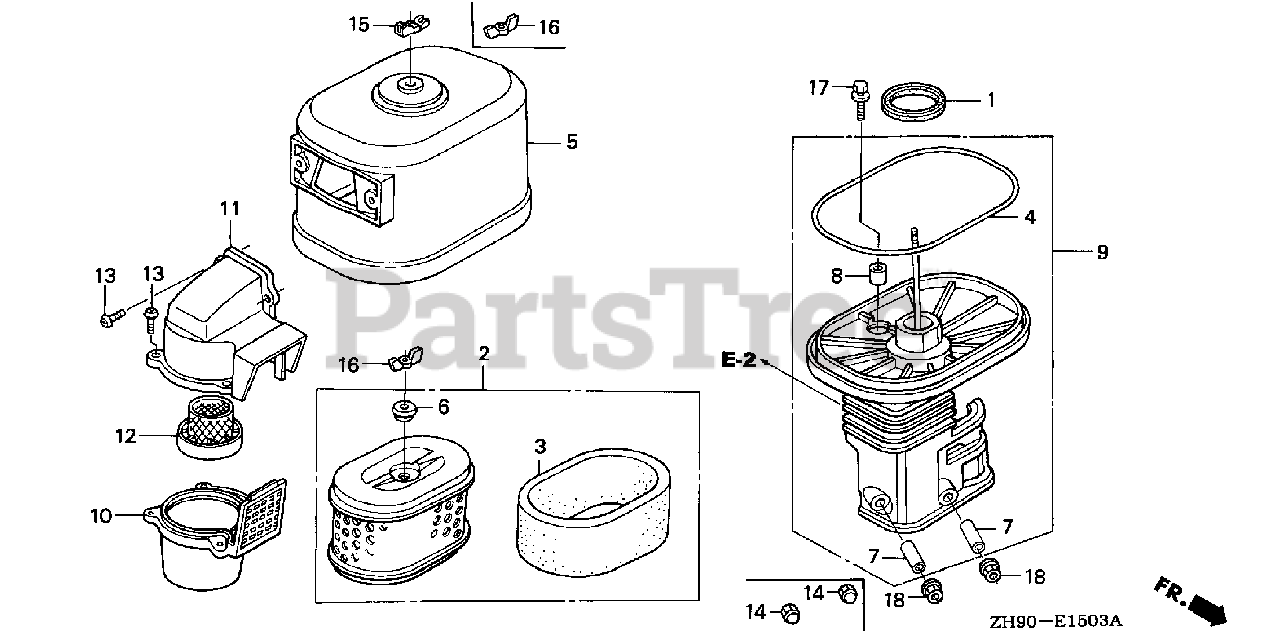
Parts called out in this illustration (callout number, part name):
1	GASKET, ELBOW
2	ELEMENT, AIR CLEANER
3	FILTER (OUTER)
4	SEAL, AIR CLEANER COVER
5	COVER, AIR CLEANER (CYCLONE)
6	GROMMET, AIR CLEANER
7	COLLAR, AIR CLEANER
8	COLLAR B, AIR CLEANER
9	ELBOW, AIR CLEANER
10	CASE, PRE AIR CLEANER
11	CAP, PRE AIR CLEANER
12	GUIDE, PRE AIR CLEANER
13	SCREW, PAN (5X16.5)
16	WINGNUT, TOOL BOX SETTING
17	BOLT-WASHER (6X22)
18	NUT, FLANGE (6MM)
